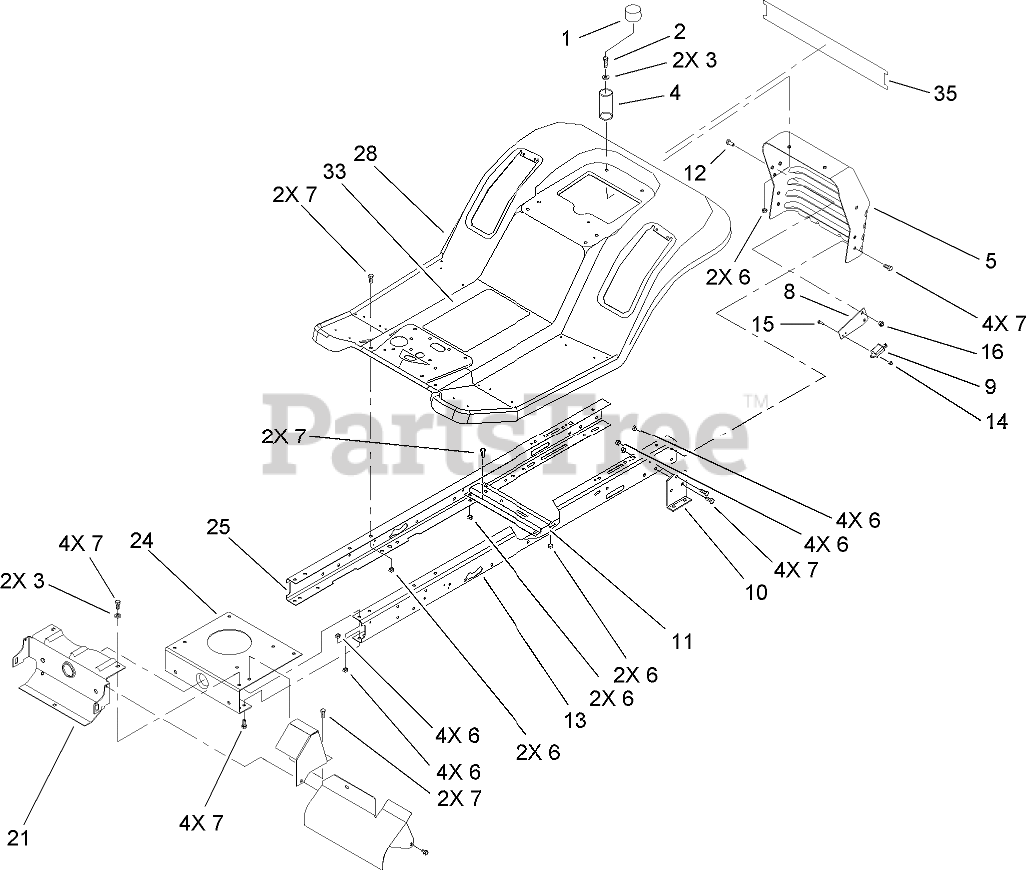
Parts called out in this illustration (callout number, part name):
1	CAP-PROTECTOR
2	SCREW-HH
3	WASHER-PLAIN
4	SPRING-COMPRESSION
5	SUPPORT-SEAT/REAR HITCH
6	NUT-LOCK, NI
7	SCREW-HH
8	PLATE-SWITCH
9	SWITCH-POLE, SINGLE
10	BRACKET-TRANSAXLE, MOUNTING
11	BRACKET-IDLER PIVOT
12	SCREW-HH
13	RAIL-FRAME, LH
14	NUT-LOCK
15	SCREW-SHH
16	NUT-LOCK, NI
21	SUPPORT-FRONT, AXLE
24	PLATE-MOUNTING, ENGINE
25	RAIL-FRAME, RH
28	REAR BODY ASM
33	DECAL-INSTRUCTION, GEAR
35	DECAL-REAR FENDER, LAWN TRACTORS
